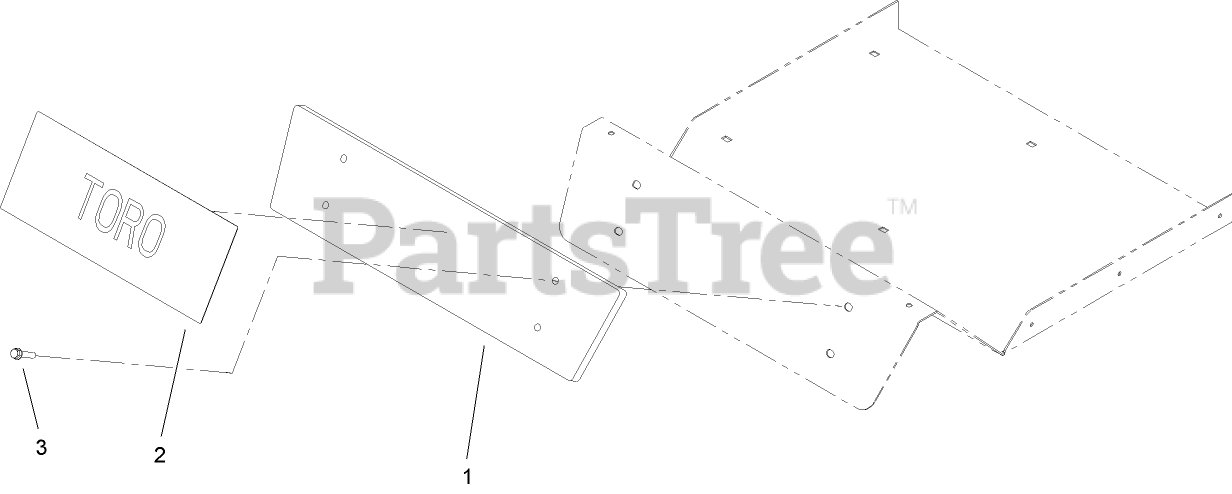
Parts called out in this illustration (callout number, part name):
1	WEIGHT-BAGGER
2	DECAL
3	SCREW-HHF
